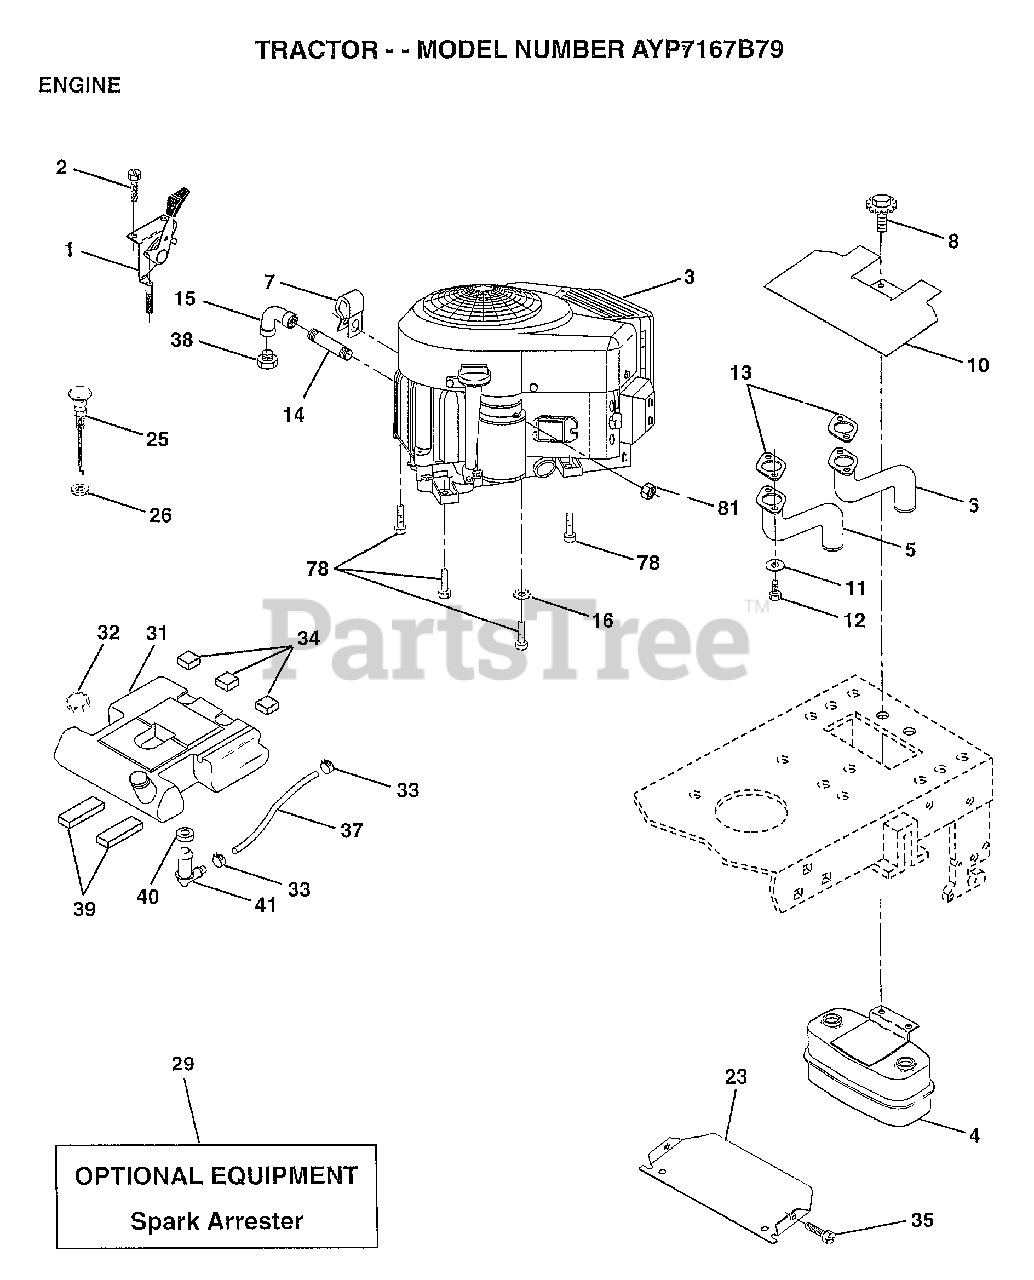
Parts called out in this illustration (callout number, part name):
1	CONTROL THROT. LH
2	SCREW LT
4	MUFFLER.TW.LOTONE
5	TUBE ASSY EXH LH
6	TUBE ASSY EXH RH
7	CLAMP.TUBE.DBL.EN
8	BOLT.5/16-18.UNC
10	SHIELD.HEAT.
14	PIPE NIPPLE LT
15	ELBOW
16	LOCKWASHER
23	SHIELD-HEAT
25	CONTROL.CHOKE.37
26	"NUT,KEPS 3/8-24IM"
31	TANK FUEL REAR
32	CAP ASM FUEL
33	HOSE CLAMP
34	PAD-SPACER LT
34	SCREW
37	FUEL LINE T
39	PAD IDLER TI
40	BUSHING OUTLET T
41	STEM.TANK.FUEL
78	SCREW
81	NUT
